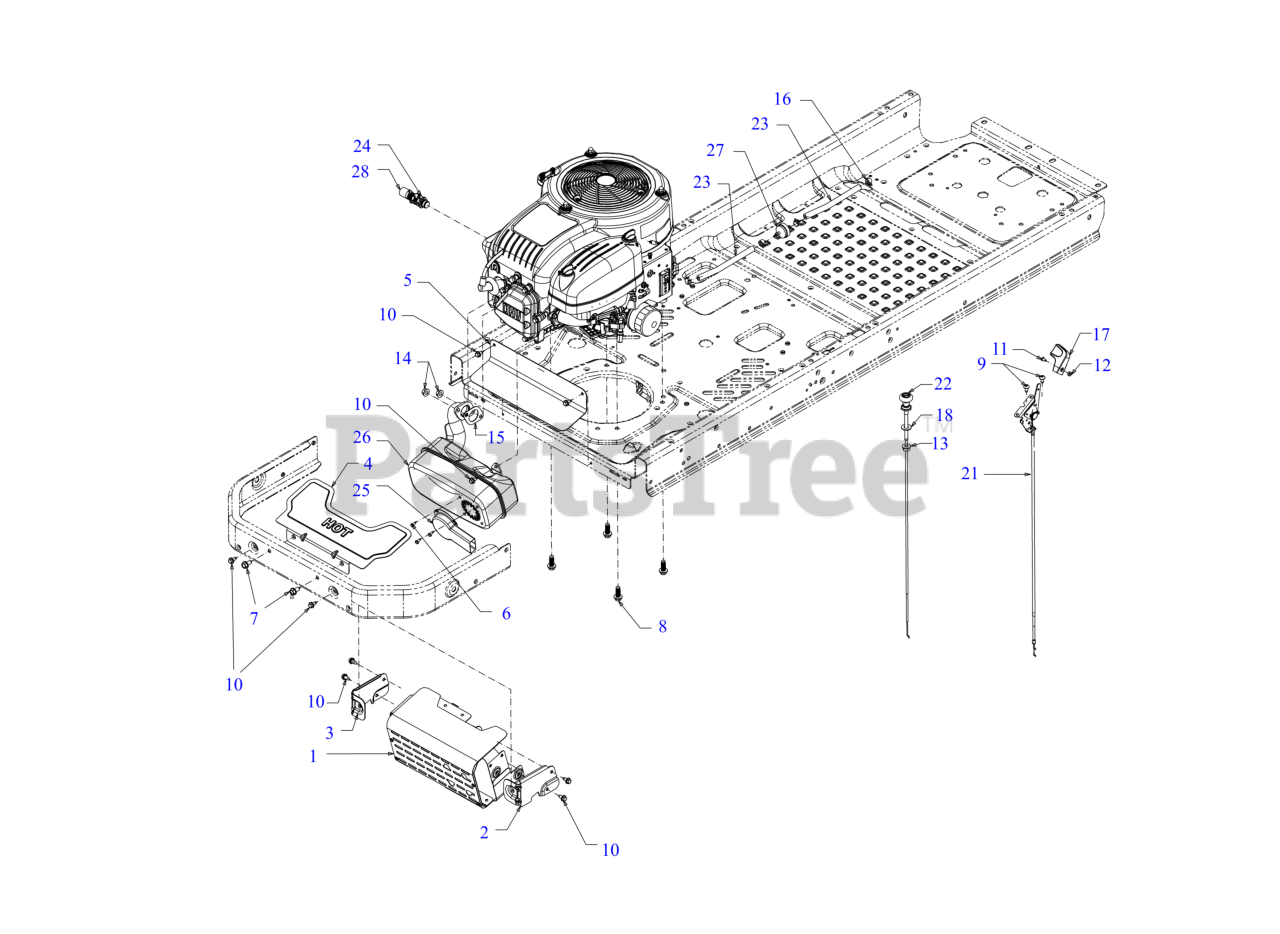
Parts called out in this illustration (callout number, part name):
5	LOWER HEAT SHIELD
6	HEX SCREW WASHER HD #8-18 x 0.500
7	SCREW 5/16-18 x .750
8	SCREW 3/8-16 x 1
9	SCREW 1/4-20 x .5
10	SCREW 1/4-20X.625
11	SCREW #8-32X.38 LG
12	HEX NUT 8-32
13	HEX FLANGE NUT
14	HEX FLANGE NUT M8X
15	EXHAUST GASKET
16	HOSE CLAMP 1/20
17	THROTTLE CONTROL KNOB
18	FLAT WASHER
21	THROTTLE CABLE 23" x .62
22	CHOKE CABLE
23	FUEL HOSE LOW PERMEATION
24	OIL DRAIN VALVE
25	EXHAUST DELECTOR
26	MUFFLER (SINGLE)
27	FUEL FILTER
28	DRAIN HOSE 14''
